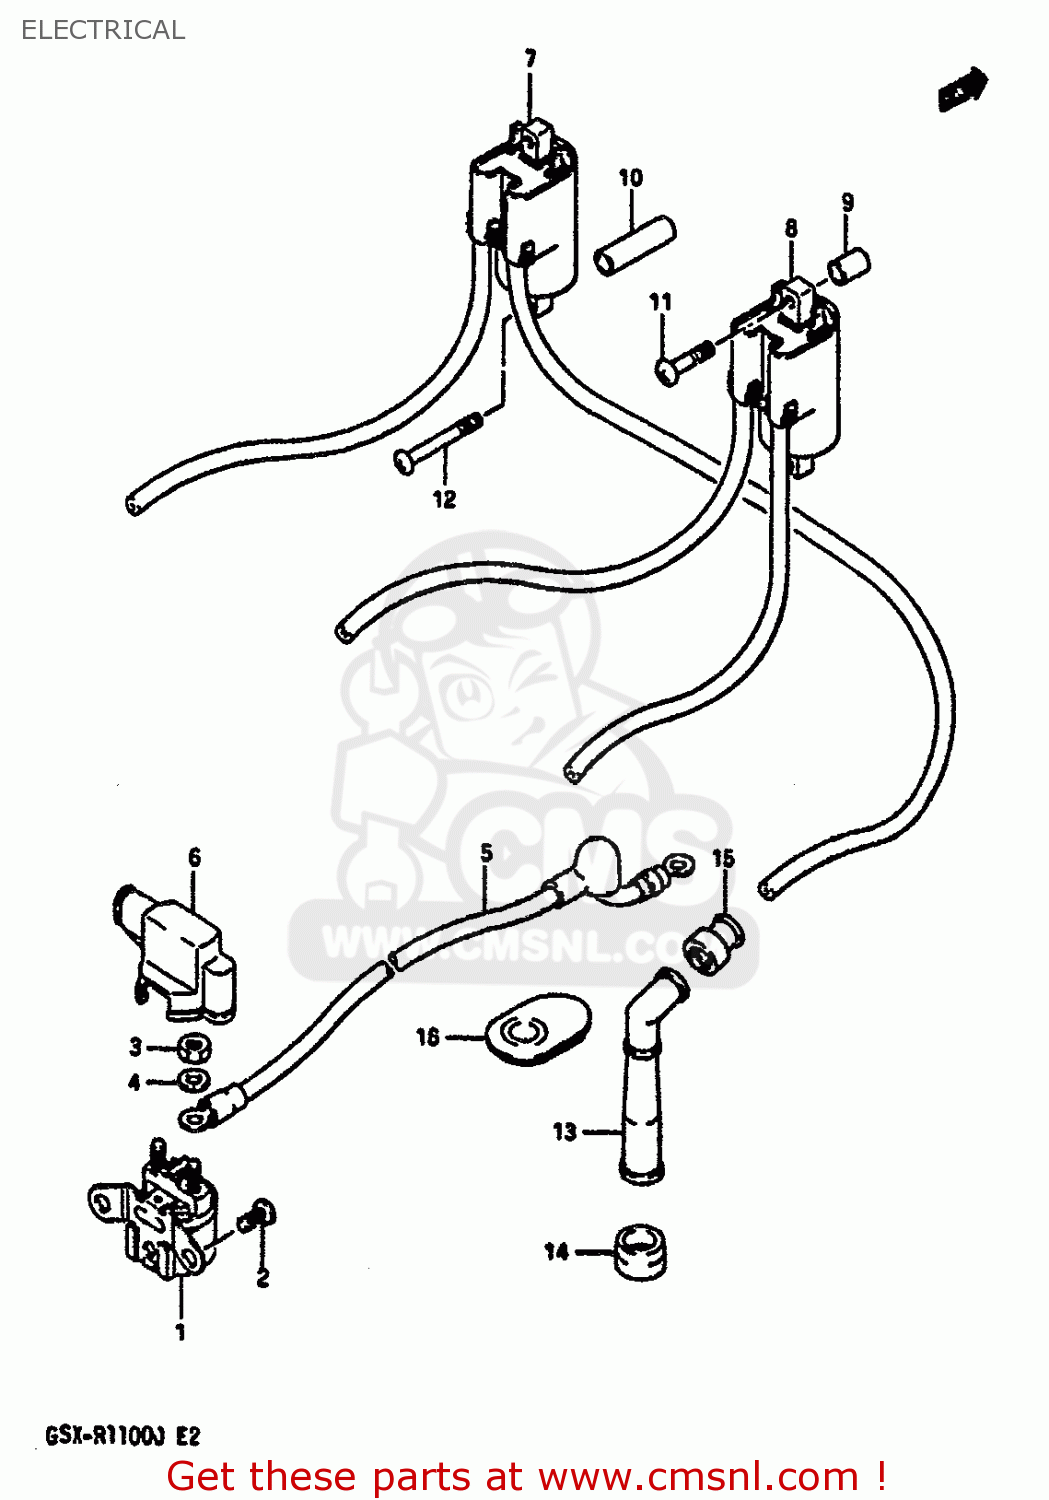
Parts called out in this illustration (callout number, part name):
1	RELAY ASSY,STARTING MOTOR
2	SCREW
3	NUT
4	WASHER,LOCK
5	WIRE,STARTER MOTOR LEAD
6	CAP,STARTER RELAY
7	COIL ASSEMBLY,IGNITION
8	COIL ASSEMBLY,IGNITION
9	SPACER
10	SPACER(6.5X10.5X40)
11	SCREW
12	SCREW
13	CAP,SPARK PLUG
14	SEAL,SPARK PLUG
15	SEAL,SPARK PLU
16	COVER,SPARK PLUG CAP
